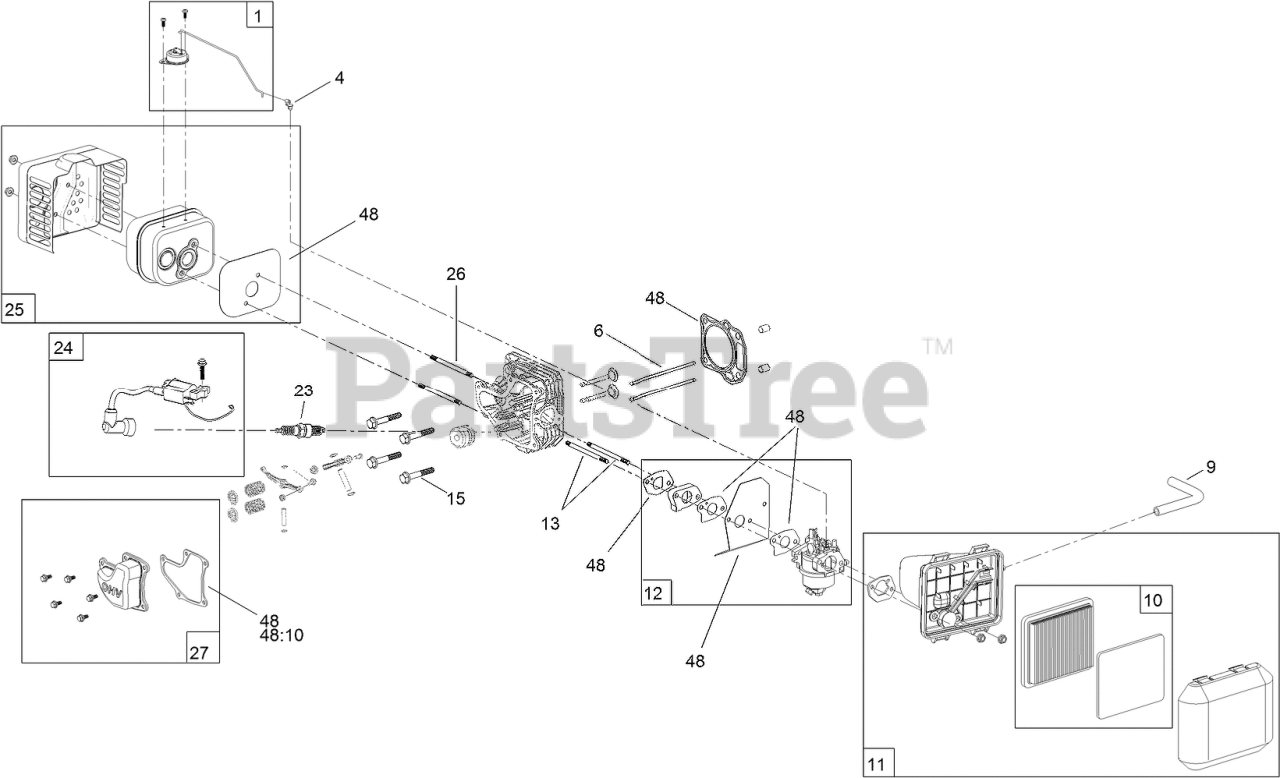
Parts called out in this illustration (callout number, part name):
1	THERMAL CONTROL KIT
4	LOCK-THROTTLE
6	ROD-PUSH
9	TUBE-BREATHER
10	AIR FILTER AND PREFILTER KIT
11	AIR CLEANER ASM KIT
12	INTERNAL CARB KIT WITH GASKETS
13	STUD-INTAKE
15	BOLT-FLANGE
23	SPARK PLUG
25	MUFFLER AND SHIELD KIT
26	STUD-EXHAUST
27	VALVE COVER KIT
48	SEAL AND GASKET KIT
48:10	GASKET-VALVE COVER
